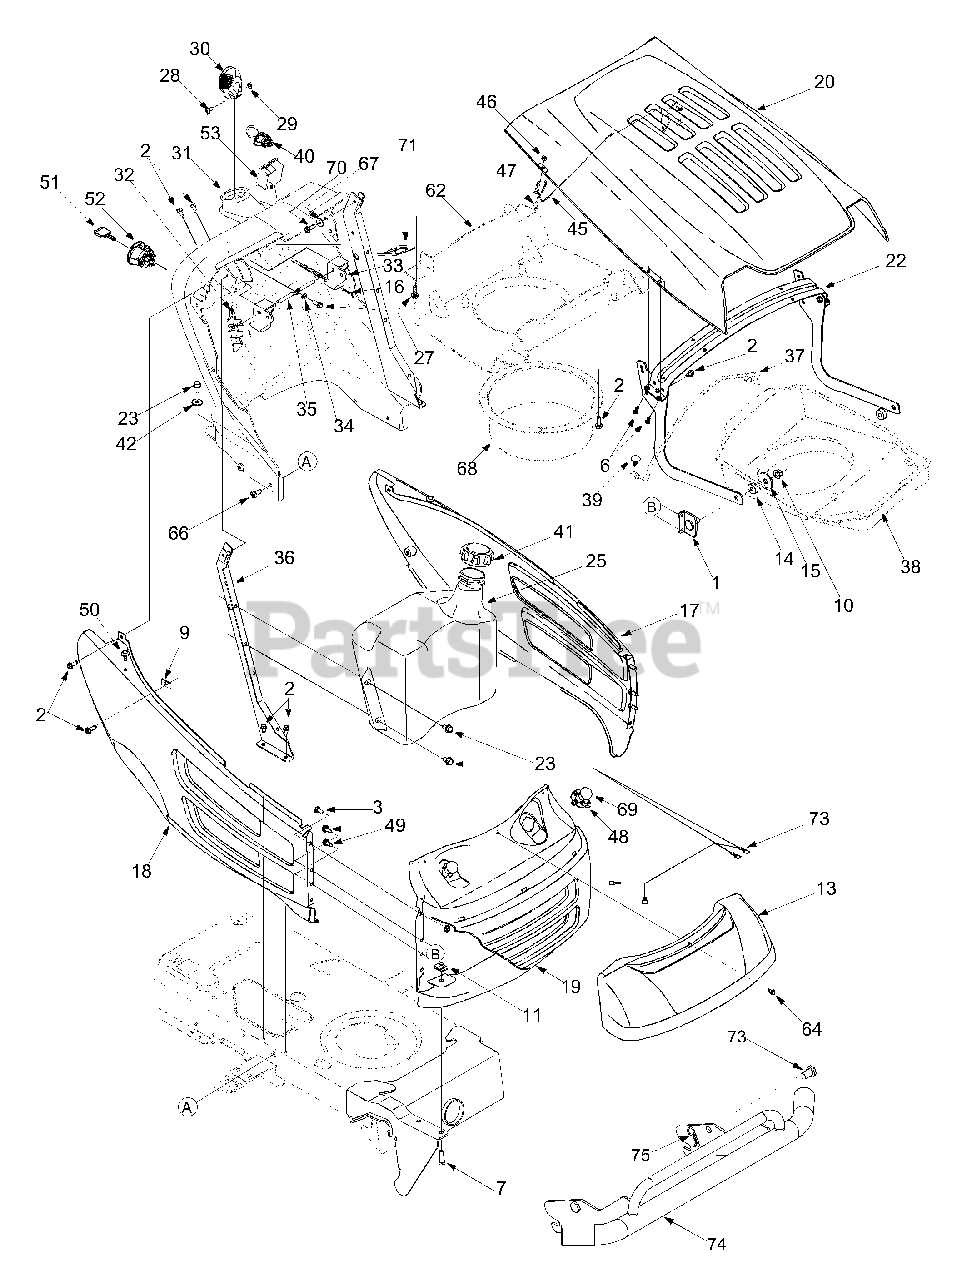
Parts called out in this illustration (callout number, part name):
2	Self-tapping Screw, 1/4-20 x .5
3	Hex Cap Screw, 1/4-20 x .62
4	Phillips Pan Screw, 1/4-20 x .75
6	Screw, #10-16 x .5
7	Hex Cap Screw, 5/16-18 x 1.0
8	Hex Sems Nut, 1/4-20
9	U-type Speed Nut, 1/4-20
10	Flange Lock Nut, 3/8-16
11	U-nut, 5/16-18
13	Headlight Lens
14	Rubber Washer, .87 x .33
15	Flat Washer, .406 x 1.5 x 11GA
16	Choke Knob/Cable (B&S Twin)
24	Fuel Tank, Three Gallon
25	Fuel Cap (fits either tank)
26	Self-tapping Screw, 1/4-20 x 1.25
27	Self-tapping Screw, 1/4-15 x .75
28	Truss Phillips Screw, #8-32 x .375
29	Hex Nut, #8-32
30	Throttle Control Knob
31	Dash Panel
32	Cruise Control Button
33	Parking Brake Button
34	Flat Washer, 9/32 x 1/2 x 1/16
35	Brake/Cruise Pivot Rod
38	Hood Plenum (B&S OHV V-Twin)
39	Ratchet Clip
40	Electric PTO Switch
41	Hex Flange Lock Nut, 1/4-20
42	Flat Washer, .349 x 1.0 x .063
45	Hood Latch
46	Hex Sems Nut, #10-32
47	Machine Screw, #10-24
48	Headlight Socket
49	Hex Index Washer Scr., 1/4-14 x .0625
50	Rubber Bumper
51	Ignition Key w/ plastic cover
52	Ignition Switch
53	Systems Ind. Monitor w/ Hour Meter
58	Clevis Pin, .50 x .78
59	Bumper Assembly
60	Internal Cotter Pin
61	Hood, Red
62	Hood Plenum
65	Choke Plug
66	Screw, 5/16-18 x .75
67	Bell Washer, .265 x .75 x .062
68	Intake Bellow (Intek Single & kohler)
69	Lamp
70	Self-tapping Screw, 1/4-20 x .75
71	Bracket: Elec. PTO Switch
72	Headlight Wire Harness
73	Clevis Pin, .50 x .78
74	Bumper Assembly
75	Internal Cotter Pin
